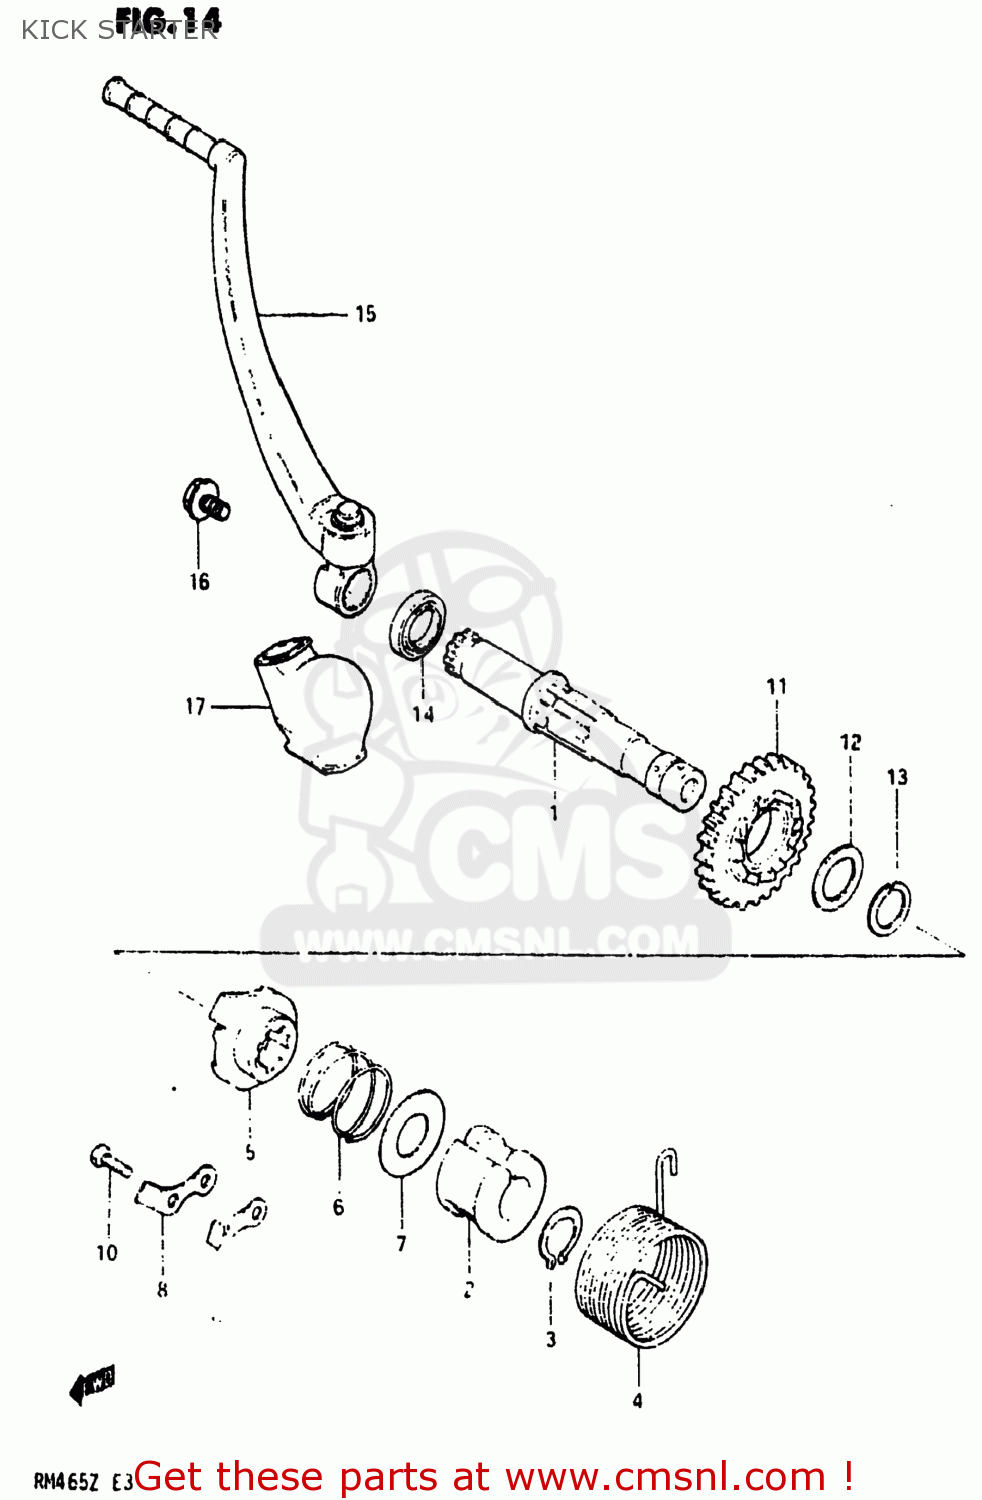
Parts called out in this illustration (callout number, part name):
1	SHAFT,KICK STARTER
2	GUIDE,KICK STARTER SFT SPRING
3	CIRCLIP
4	SPRING
5	STARTER,KICK
6	SPRING
7	WASHER
8	GUIDE,KICK STARTER
9	STOPPER,KICK STARTER
10	BOLT(8X20)
11	GEAR,KICK STARTER DRIVE
12	SHIM
13	CIRCLIP
14	SEAL,OIL(20X27X5)
15	LEVER ASSEMBLY,KICK STARTER
16	BOLT(8X14)
17	COVER,KICK STARTER LEVER JOINT
